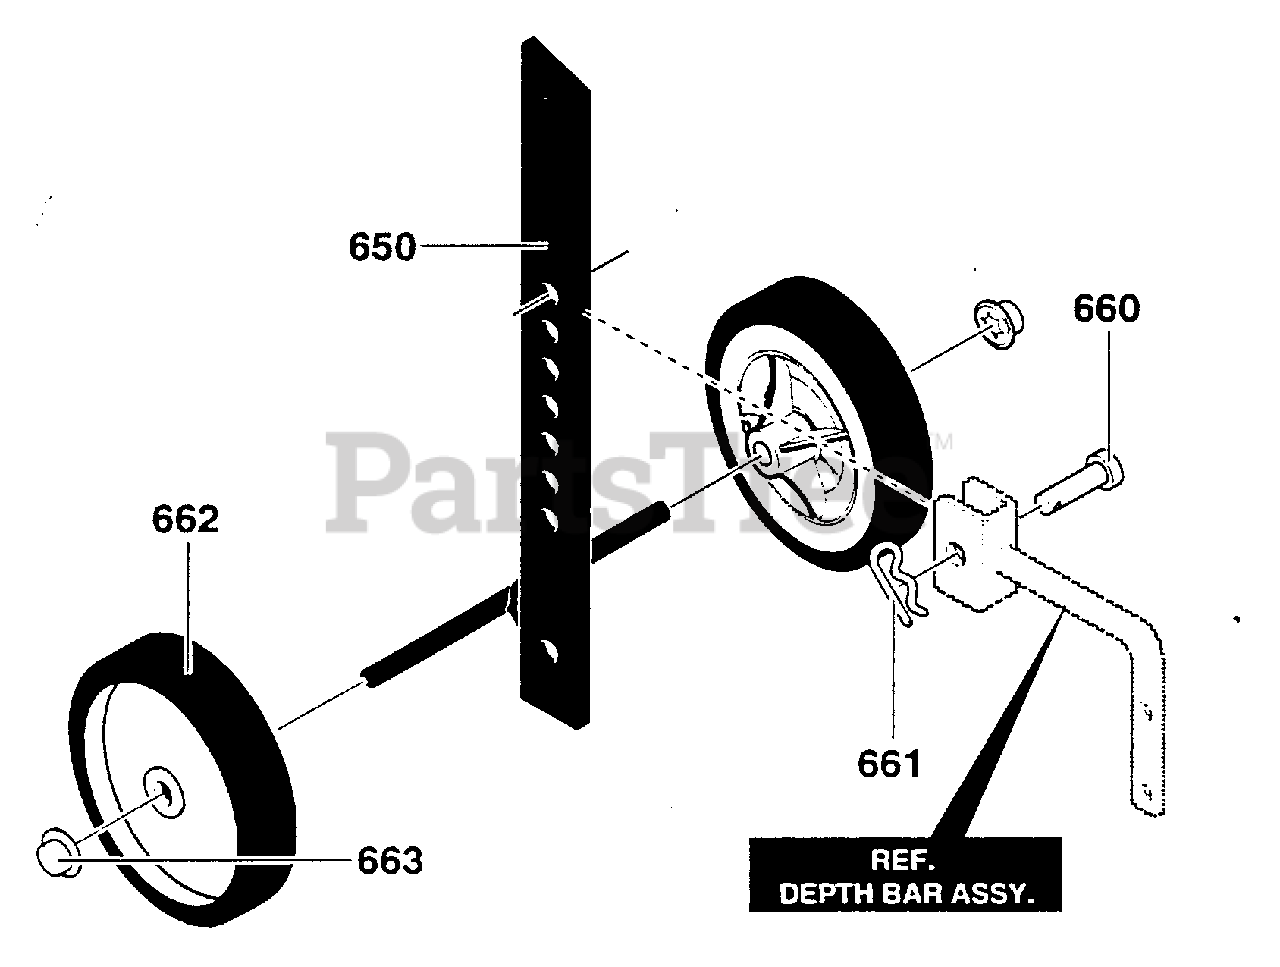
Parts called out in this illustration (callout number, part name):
650	WHEEL SUPT,ASSY
660	PIN, CLEVIS .321 X.75BR
661	PIN, HAIR .53 DIA X 1.62LG
662	TIRE & RIM,SEPU 5.0 X 1.(696)
663	NUT, PUSH ON 3/8"
